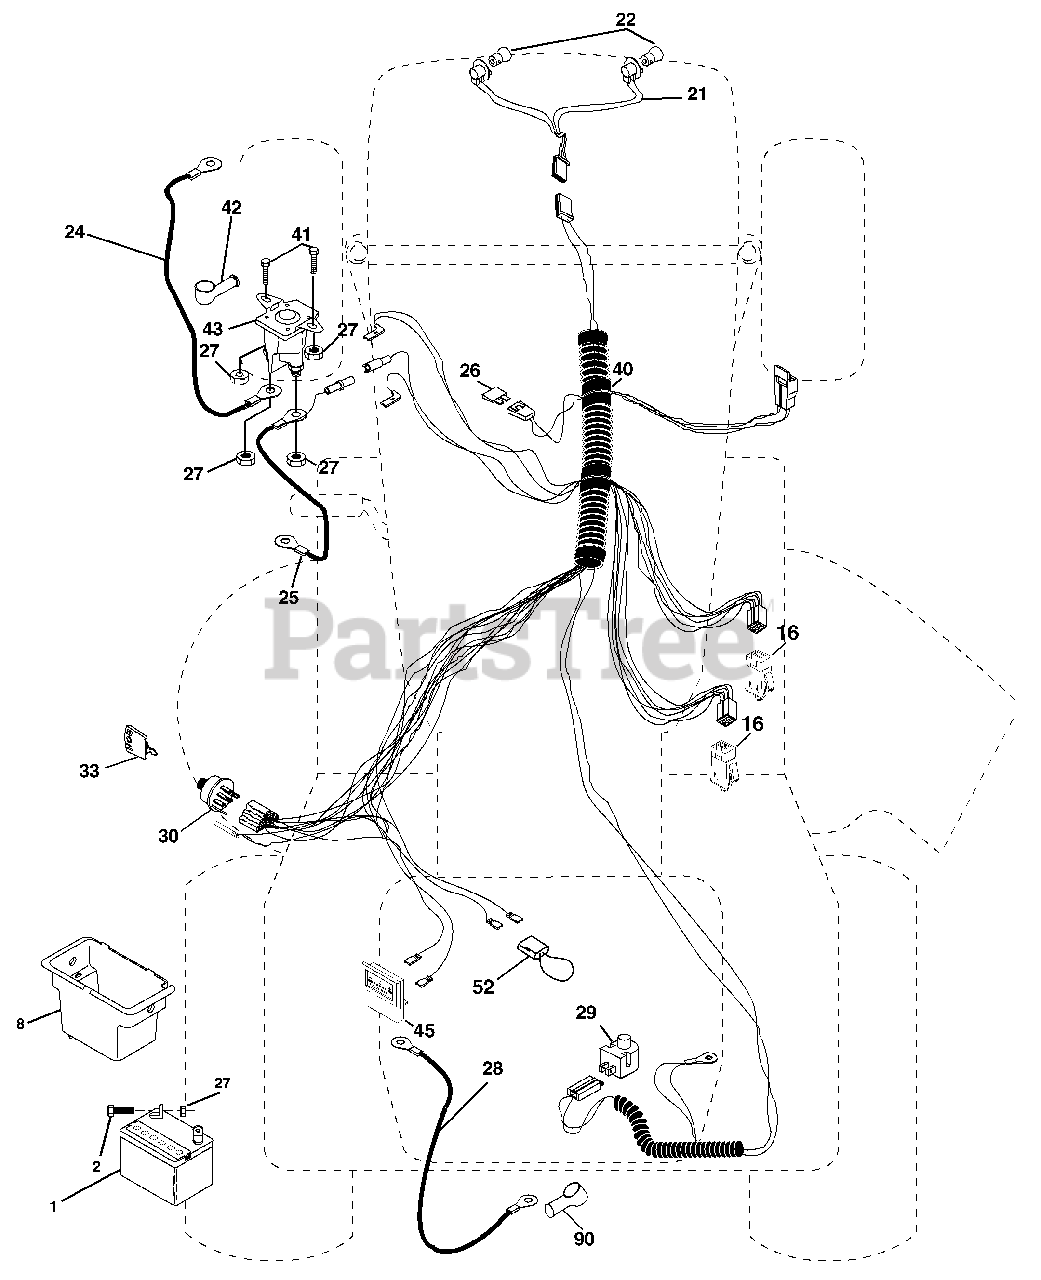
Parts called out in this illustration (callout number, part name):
1	Battery
2	Bolt Hex Hd 1/4-20 unc x 3/4
8	Box Battery
16	Switch Interlock
21	Harness Socket Light
22	Bulb, Light # 1156
24	Cable Battery
25	Cable Battery 6 Ga. Red w/16 wire 44"
26	Fuse
27	Nut Keps Hex 1/4-20 unc
28	Cable Ground 12" Blk 6 Ga.
29	Switch Plunger Nc Gray
30	Switch Ign
33	Key Ign Molded Generic
40	Harness Ign
41	Bolt Fin Hex 1/4-20 unc x 1/2
42	Cover Terminal Red
43	Solenoid
45	Ammeter Rectangular
52	Protection Loop
90	Cover Terminal
